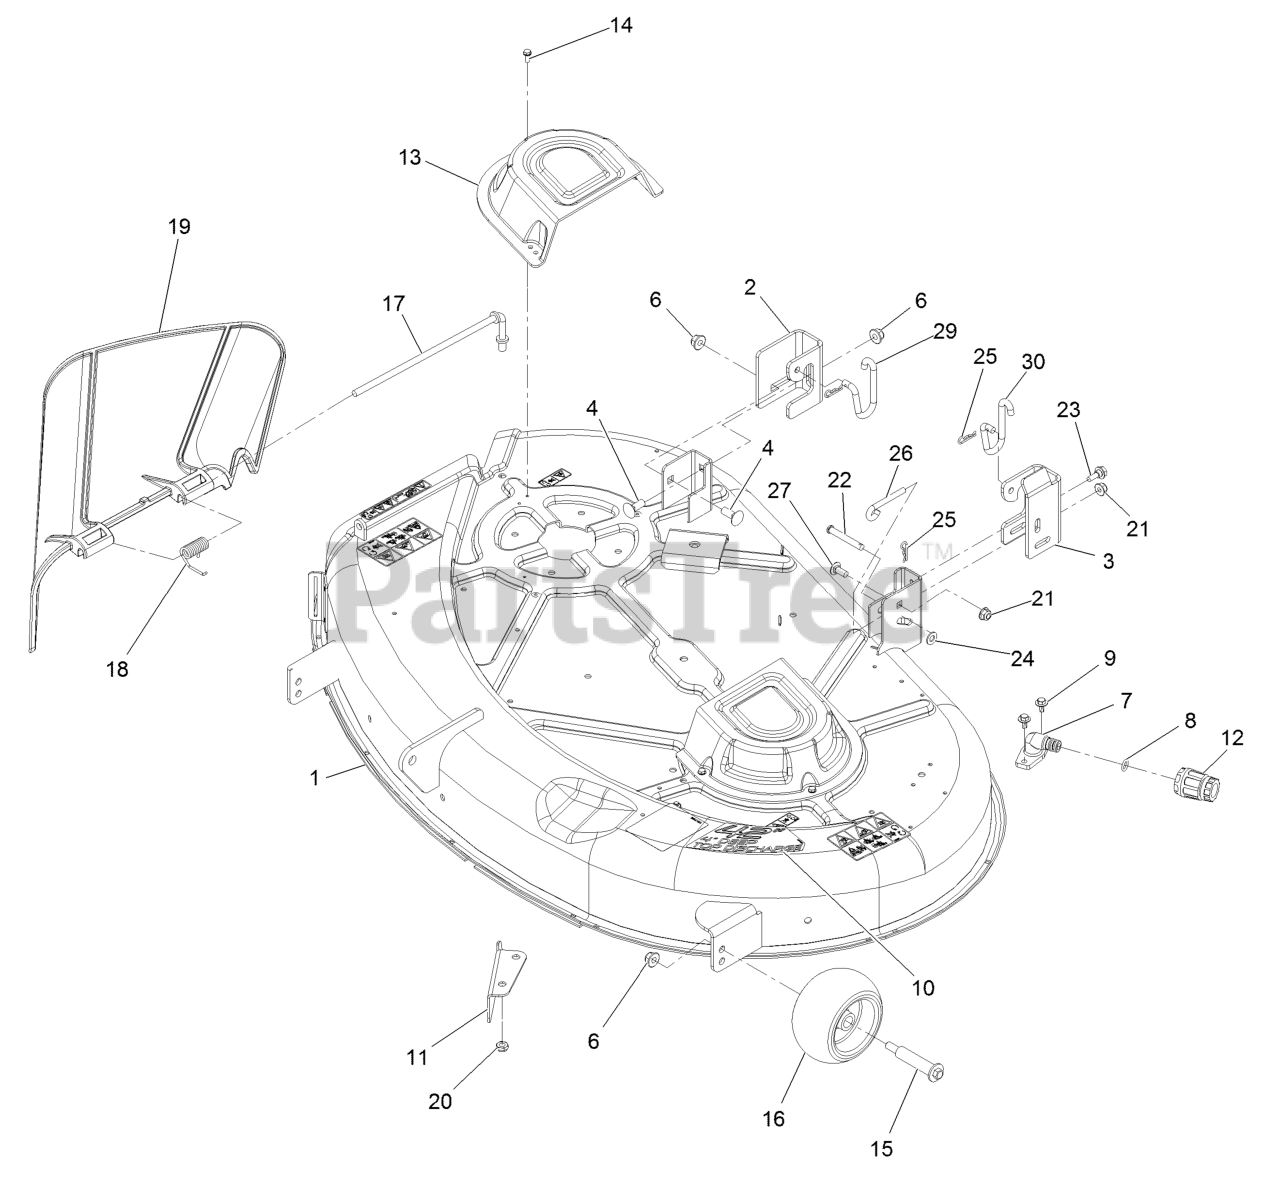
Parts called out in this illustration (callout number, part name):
1	42 INCH DECK AND DECAL AS
2	BRACKET-HANGER, RH
3	BRACKET-HANGER, LH
4	BOLT-CARR
6	NUT-HF, NI
9	SCREW-HHFTF
11	BAFFLE-CUTOFF
12	CONNECTOR-HOSE
13	COVER-BELT
14	SCREW-TAPTITE
15	BOLT-SHOULDER
16	ROLLER-SCALP, ANTI
17	ROD-PIVOT
18	SPRING-TORSION
19	DEFLECTOR
21	NUT-HF, NI
22	PIN-CLEVIS
23	SCREW-SHOULDER,HWH
24	WASHER-PLAIN
25	PIN-COTTER
26	ROD-LEVEL, DECK
27	SCREW-CARR
29	LINK-RETENTION, DECK (RH)
30	LINK-RETENTION, DECK (LH)
